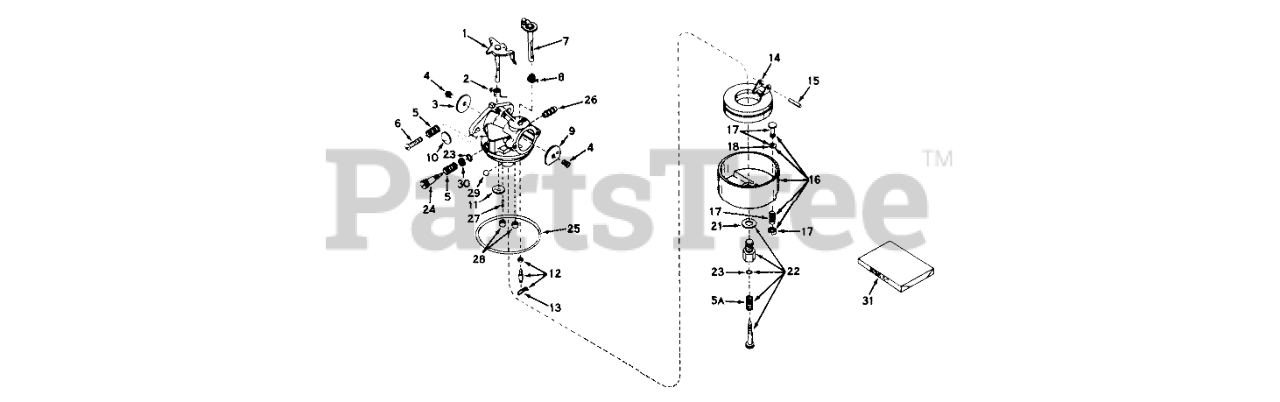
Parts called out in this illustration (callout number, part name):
1	Shaft/Lever-Throttle
2	Spring, Return
3	Shutter-Throttle
4	Screw-Shutter
5	Spring-Tension
6	Screw-Throttle Crack Screw / Idle Speed
7	Shaft & Lever Assy., Choke
8	Spring, Choke return
9	Shutter-Choke
10	Plug-Welch, Idle Mixture Well
11	Plug-Welch, Atmospheric Vent
12	Inlet Needle Seat & Clip Assembly (Incl. No. 13)
13	Clip-Spring
14	Float,Carburetor
15	Shaft-Float
16	Bowl & Drain Assy., Float (Incl. No. 17)
17	Drain Assembly, Bowl (Incl. No. 18)
18	Gasket-Plunger, Drain
21	Washer-Bowl Nut
22	Adjustment Screw Assy., Main (Incl. Nos. 5A, 21 & 23)
23	"O"Ring
24	Screw, Idle Adj.
25	O Ring-Bowl, Float
26	Fitting, Fuel inlet
28	Plug, Cup
29	BalI, Steel
31	Kit-Repair
